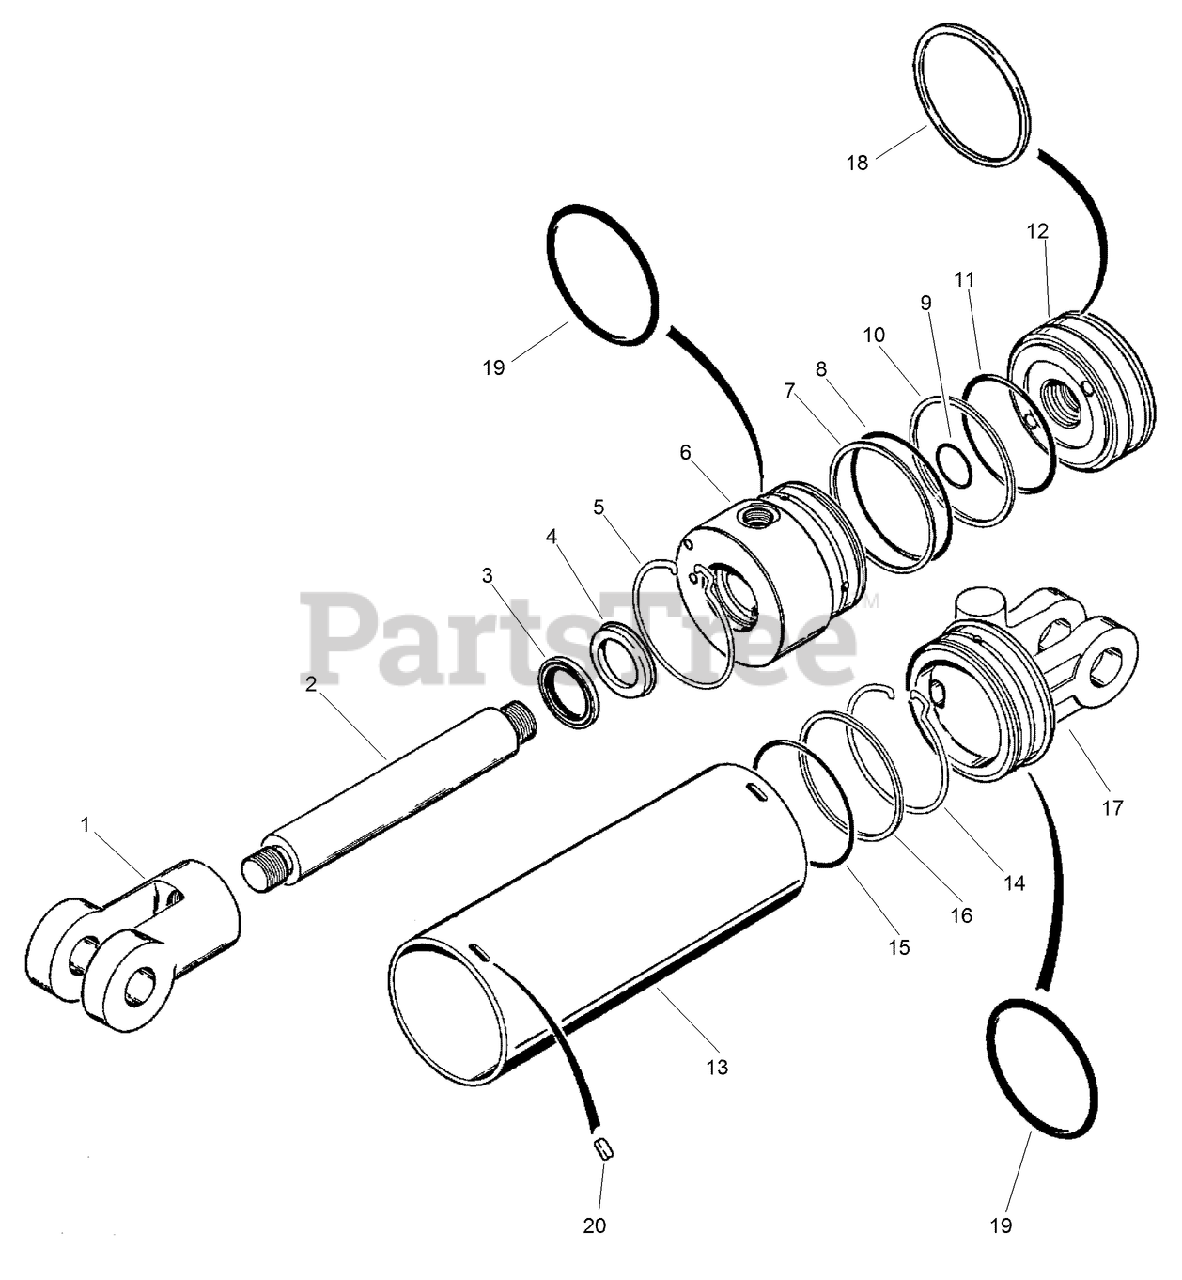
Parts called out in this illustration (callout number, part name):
1	END - Rod
2	ROD - Piston
3	WIPER - Piston Rod
4	SEAL - U-Cup, Piston Rod
5	RING - Lock
6	GLAND - Cylinder
7	RING - Backup, O-Ring
8	O-RING
9	O-RING
10	O-RING
11	SEAL
12	PISTON - Cylinder
13	TUBE - Cylinder
14	Ring, Lock
15	O-RING
16	Ring, Backup
17	HEAD - Cylinder
18	RING - Wear
19	O-RING
20	COVER - Ring, Lock
